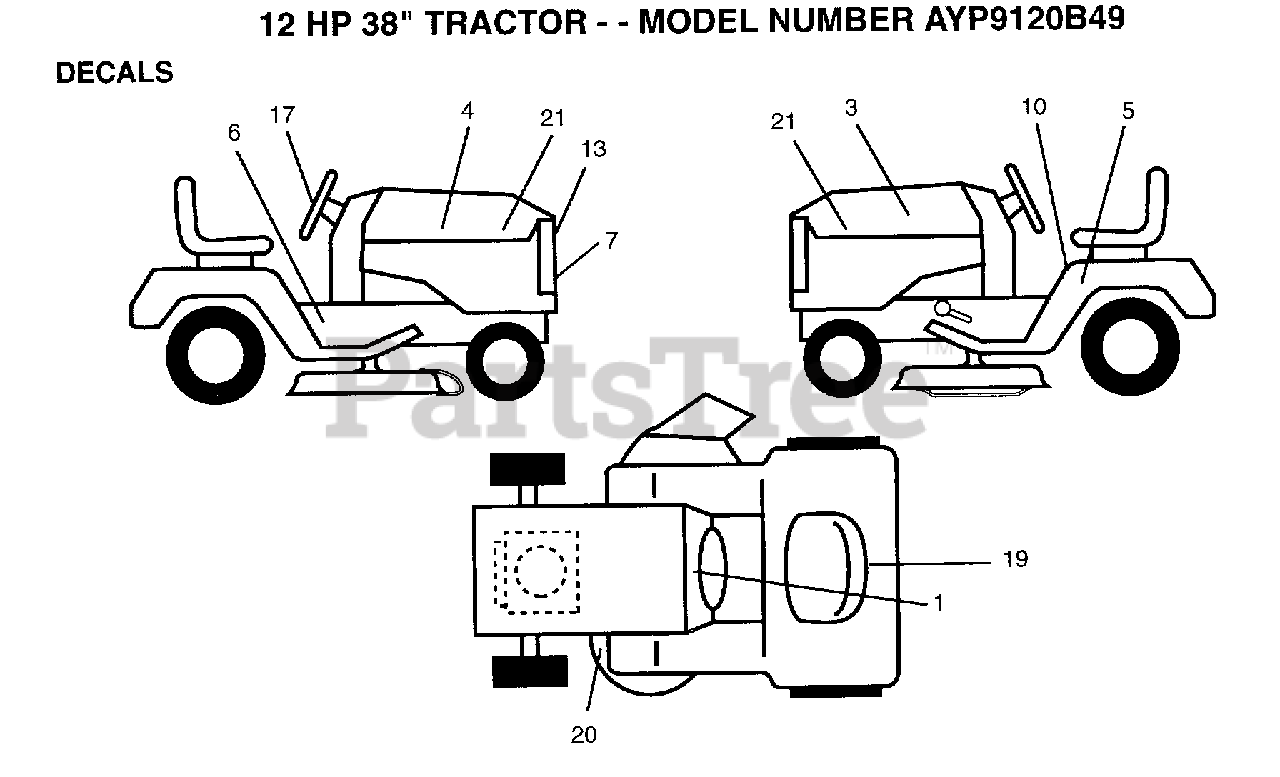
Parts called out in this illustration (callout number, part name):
1	DECAL.INST.OPER
3	DECAL STRIPE HOOD
4	DECAL STRIPE HOOD
5	DECAL
6	DECAL CHASSIS
7	"DECAL,LIGHT BOX"
10	DECAL
13	DECAL.GRILLE
20	DECAL
21	DECAL.INST.HD.WIZ
